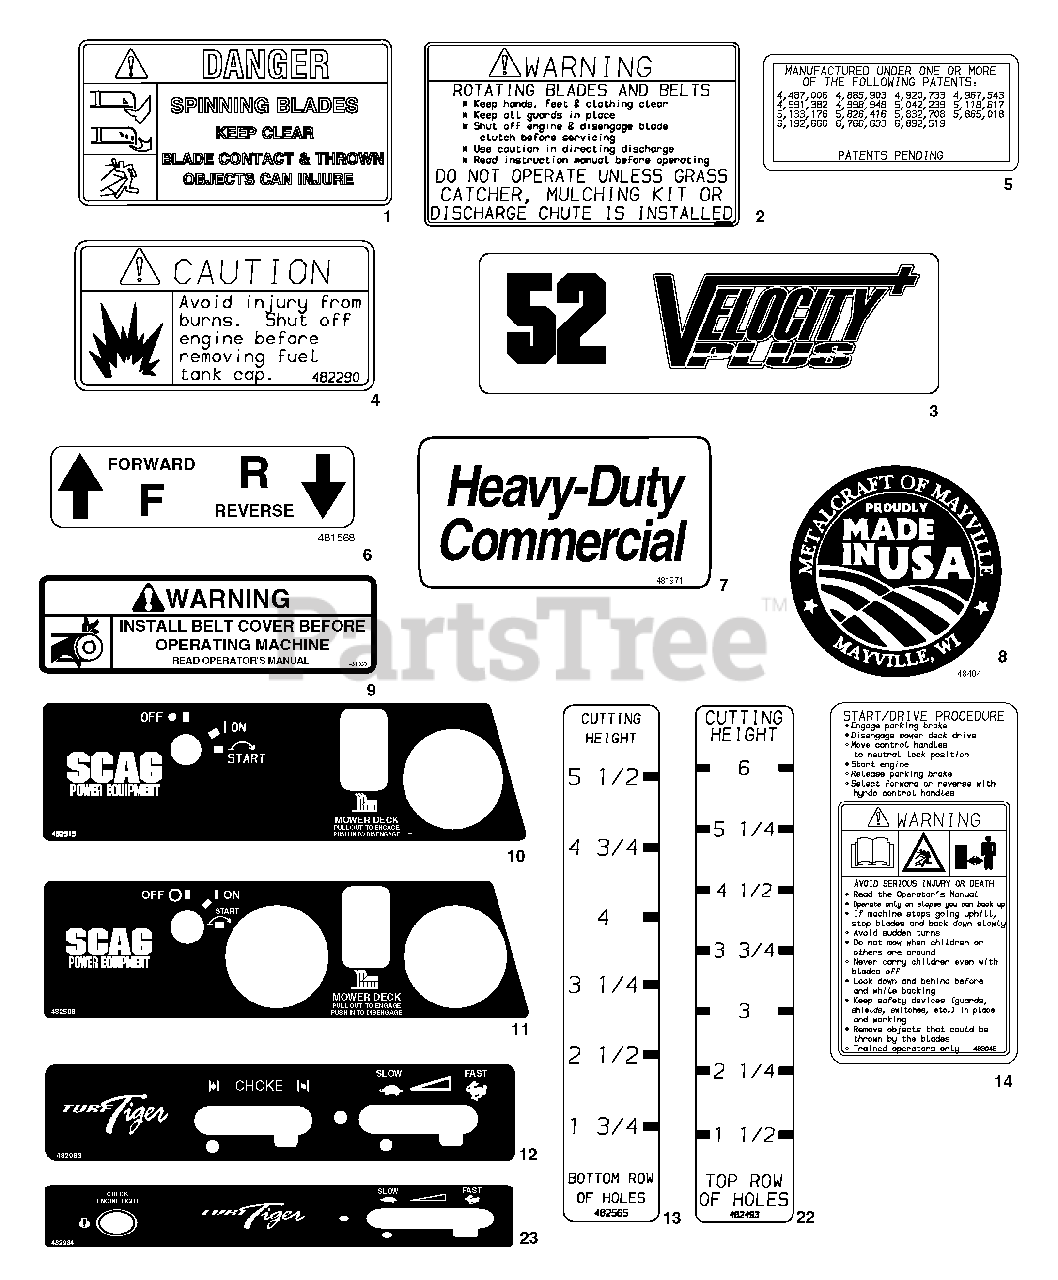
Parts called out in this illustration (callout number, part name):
1	Decal, Danger-Spinning Blades
2	Decal, Warning-Rotating Blades
3	Decal, 52 Velocity Plus
4	Decal, Fuel Tank
5	Decal, Patents
6	Decal, Traction Control
7	Decal, Heavy Duty Commercial
8	Decal, Metalcraft-Made In USA
9	Decal, Belt Cover
10	Decal, Instrument Panel-Upper (Air Cooled)
11	Decal, Instrument Panel-Upper (Kawasaki)
12	Decal, Instrument Panel-Lower
13	Decal, Cutting Height - Lower
14	Decal, Start/Drive Procedure
22	Decal, Cutting Height - Upper
23	Decal, Instrument Panel - Lower
